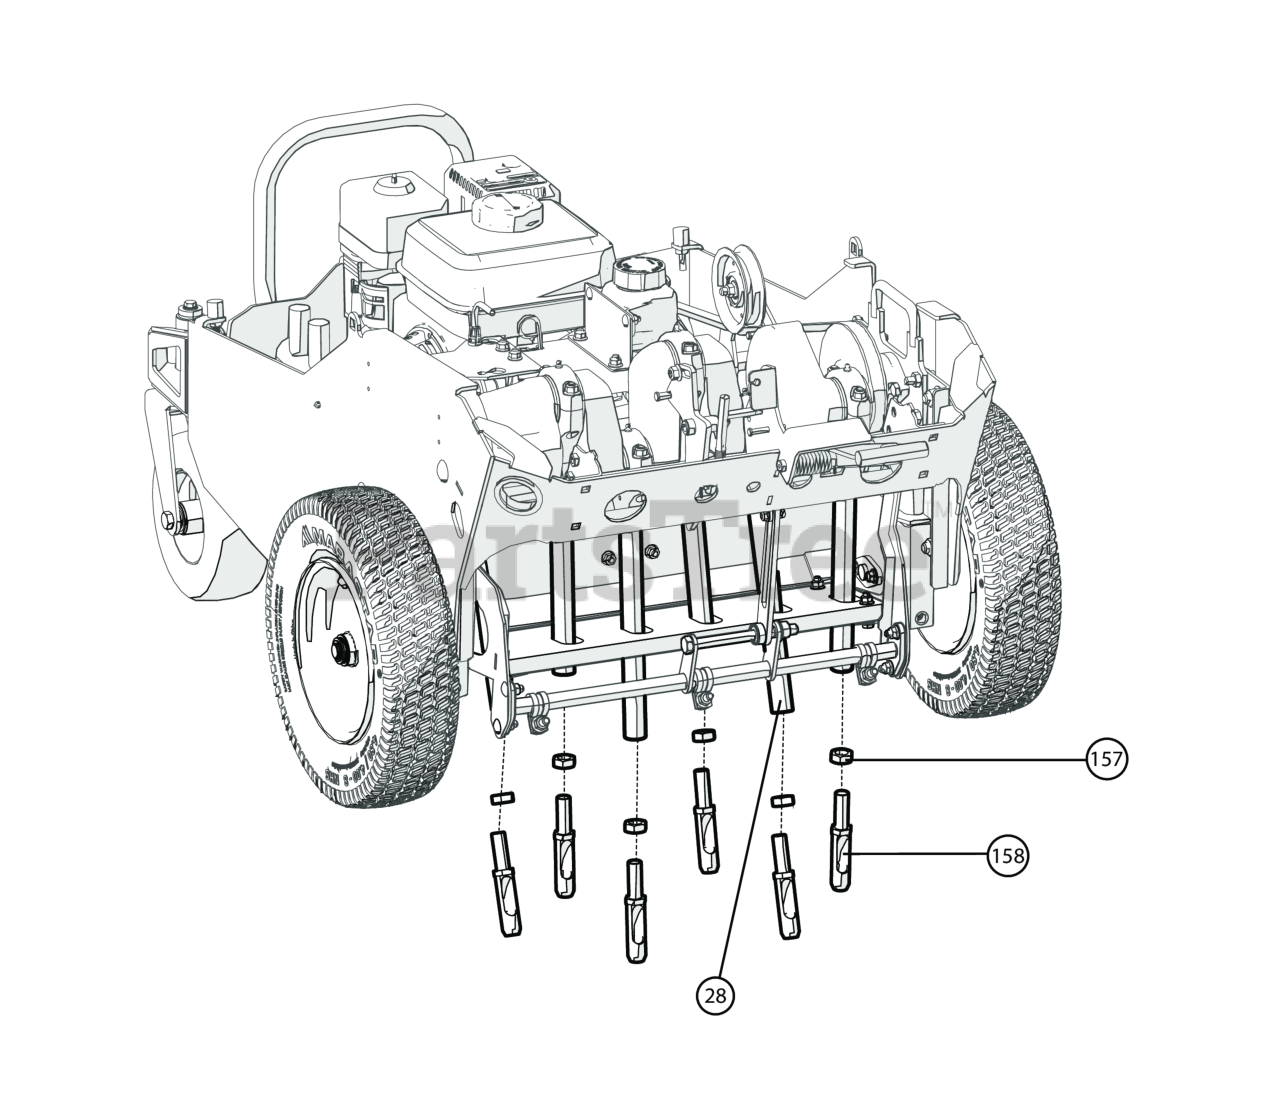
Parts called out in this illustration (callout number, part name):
28	ASM, TINE ROD AND CAP
157	NUT JAM, 5/8-11 ZP
158	TINE, PLUGR .625"-11 BLACK
